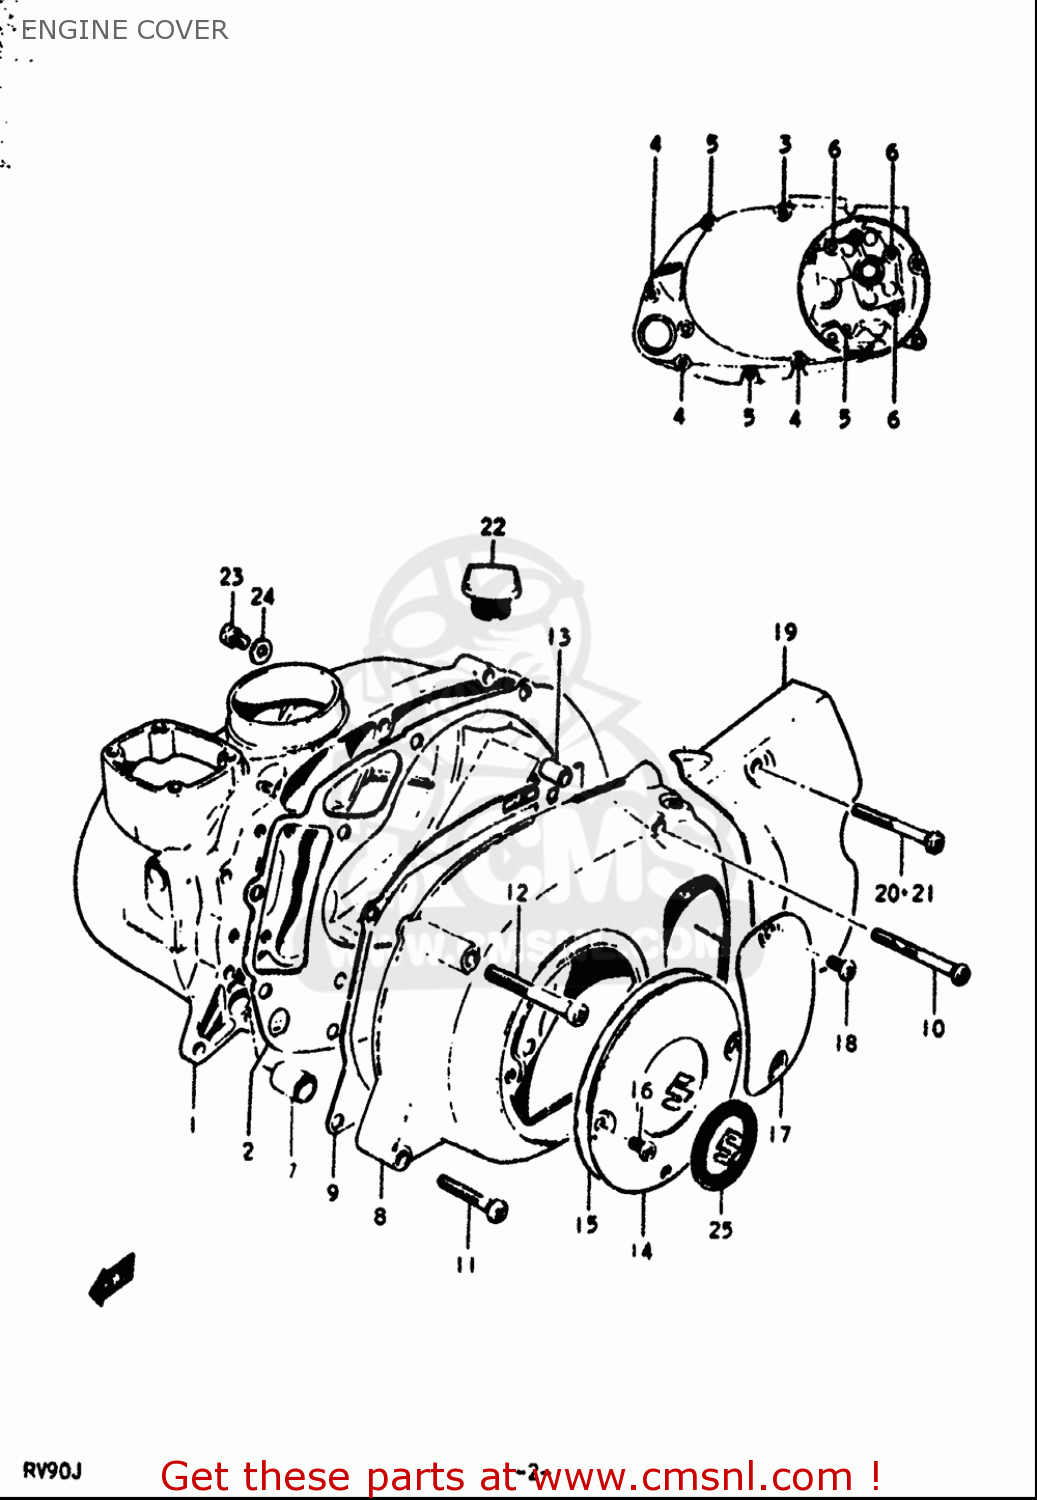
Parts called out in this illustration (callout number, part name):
1	COVER,CLUTCH
2	GASKET,CLUTCH COVER (NAS)
3	SCREW
4	SCREW
5	SCREW
6	SCREW
7	PIN
8	COVER,MAGNETO
9	GASKET,MAGNETO COVER (NAS)
10	SCREW
11	SCREW
12	SCREW
13	PIN
14	CAP,MAGNETO INSPECTION
15	GASKET,MAGNETO INSPECTION CAP (NAS)
16	SCREW
17	CAP,CLUTCH RELEASE ADJUST
18	SCREW
19	COVER,ENGINE SPROCKET
20	SCREW
21	SCREW
22	PLUG SET
23	SCREW(6X10)
24	GASKET(6.2X11X1) (NAS)
